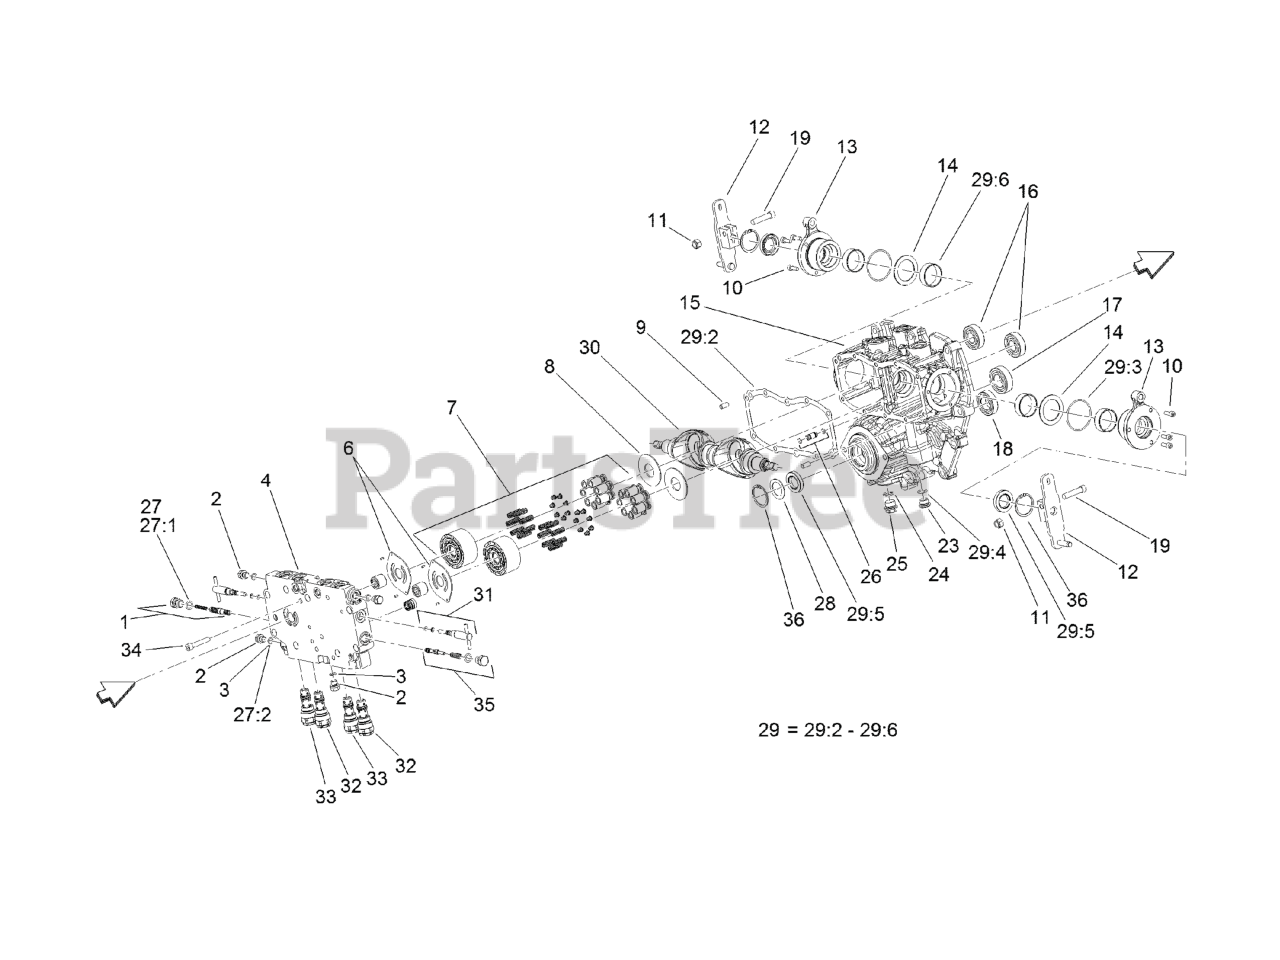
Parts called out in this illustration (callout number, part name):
1	VALVE-FLUSHING, RH
3	O RING-PLUG
4	CENTER CASE, COMPLETE
6	PLATE-VALVE
7	CYLINDER BLOCK ASM
8	PLATE-THRUST
9	PIN-PARALLEL
12	ARM-CONTROL
13	SIDE COVER ASM
15	PUMP HOUSING ASM
16	BEARING
17	BEARING
18	BEARING
23	PLUG-NPTF
24	O-RING
27	CENTER CASE SEAL KIT
27:2	O RING-PLUG
29	PUMP HOUSING SEAL KIT
29:2	GASKET-CASE, CENTER
29:3	O RING-PLUG
29:4	Packing
29:6	RING-SEAL
30	PLATE-SWASH
31	VALVE-BYPASS
32	VALVE-REAR
33	VALVE-FRONT
35	VALVE-FLUSHING, LH
36	RING-SNAP
